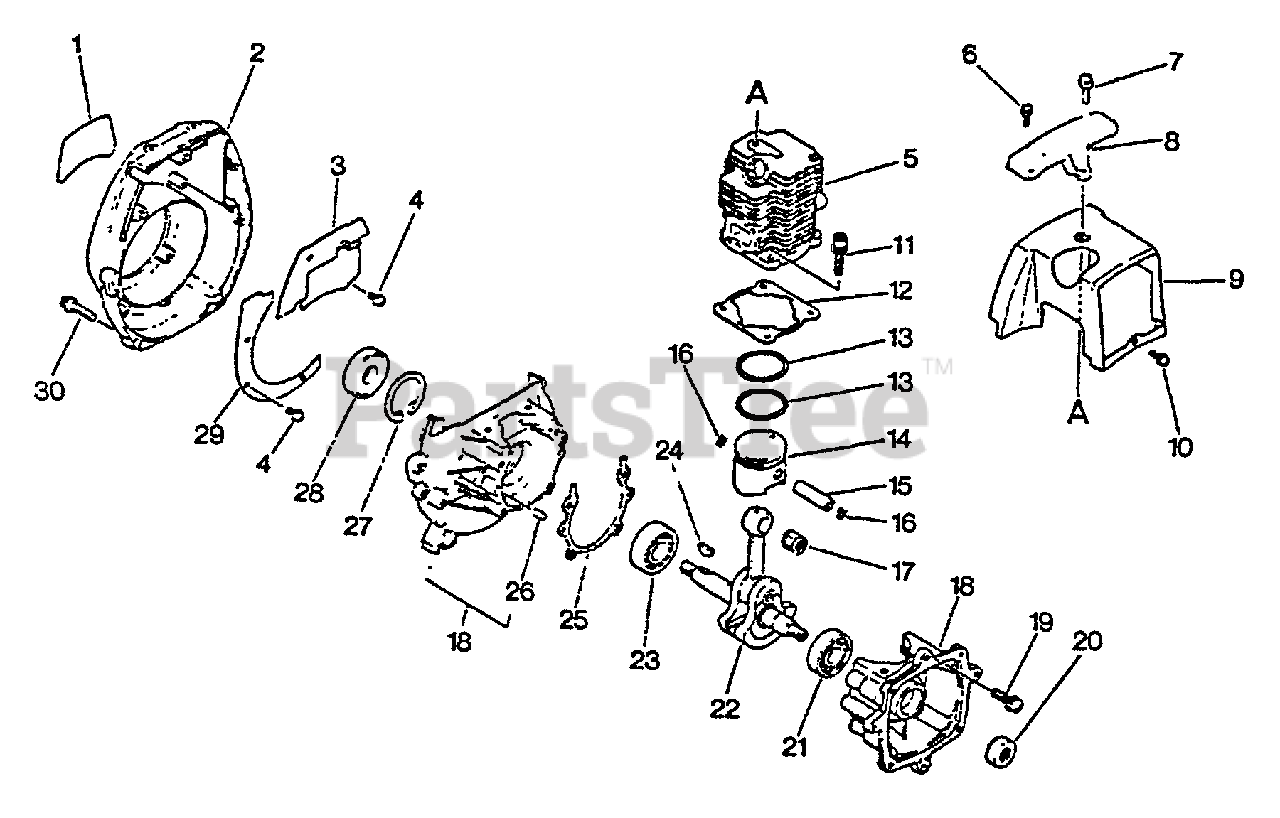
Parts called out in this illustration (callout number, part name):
1	LABEL - MODEL
2	CASE, FAN - ORANGE
3	SHIELD, FAN
4	SCREW - 4X8
5	CYLINDER
6	SCREW - 4X14
7	SCREW - 5X16
8	GUARD - TOP
9	COVER, ENGINE
10	SCREW - 4X10
11	SCREW - 5X20
12	GASKET, CYLINDER
13	RING, PISTON
14	PISTON
15	PIN, PISTON
16	RING, RETAINING
17	BEARING, NEEDLE
18	CRANKCASE KIT
19	SCREW - 5X25
20	SEAL, OIL
21	BEARING, BALL - 6001C3
22	CRANKSHAFT ASSY
23	BEARING, BALL - 6201
25	GASKET, CRANKCASE
26	PIN - LOCATING
27	RING, RETAINING - 32
28	SEAL, OIL
29	SHIELD, FAN
30	SCREW - 5X20
